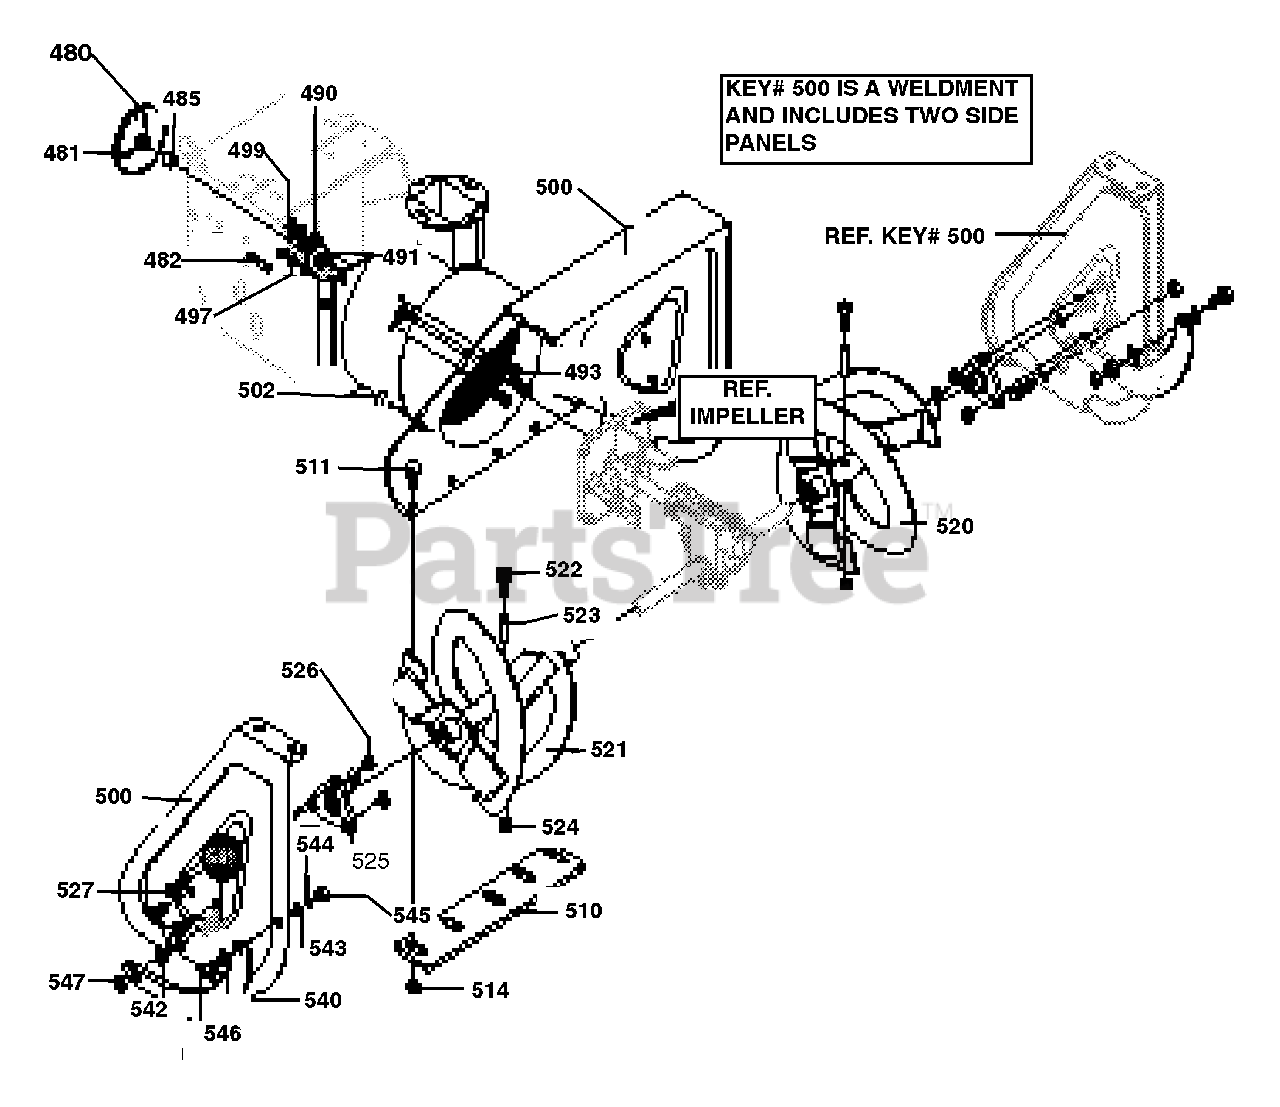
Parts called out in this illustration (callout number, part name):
480	Pulley, V4L
481	Screw, 5/16-18 x .50
482	Key, Square
485	Spacer, Slve .676 x 1.00 x .53
490	Retainer, Ball Bearing
491	Bearing, Ball
493	Screw, 5/16-18 x .75
497	Washer, .328 x .60 x .09
499	Nut, 5/16-18
500	Housing, Assy
502	Ratchet Fastener
510	Blade, Scraper 22"
511	Carr. Bolt, 1/4-20 x .75
514	Nut, 1/4-20 Whiz-loc
520	Auger, Assy LH
521	Auger, Assy RH
522	Screw, 1/4-20 x 1.75
523	Spacer, Slve .250 x .47 x .20
524	Nut, 1/4-20
525	Bearing, Flange
526	Nut, 5/16-18
527	Screw, 5/16-18 x .75
541	Bolt, 5/16-18 x .75
542	Washer, Flat
543	Washer, Flat
544	Washer, Splitlock
545	Nut, 5/16-18
546	Screw, 5/16-18 x .75
647	Nut, 5/16-18, HXWDFLLK
